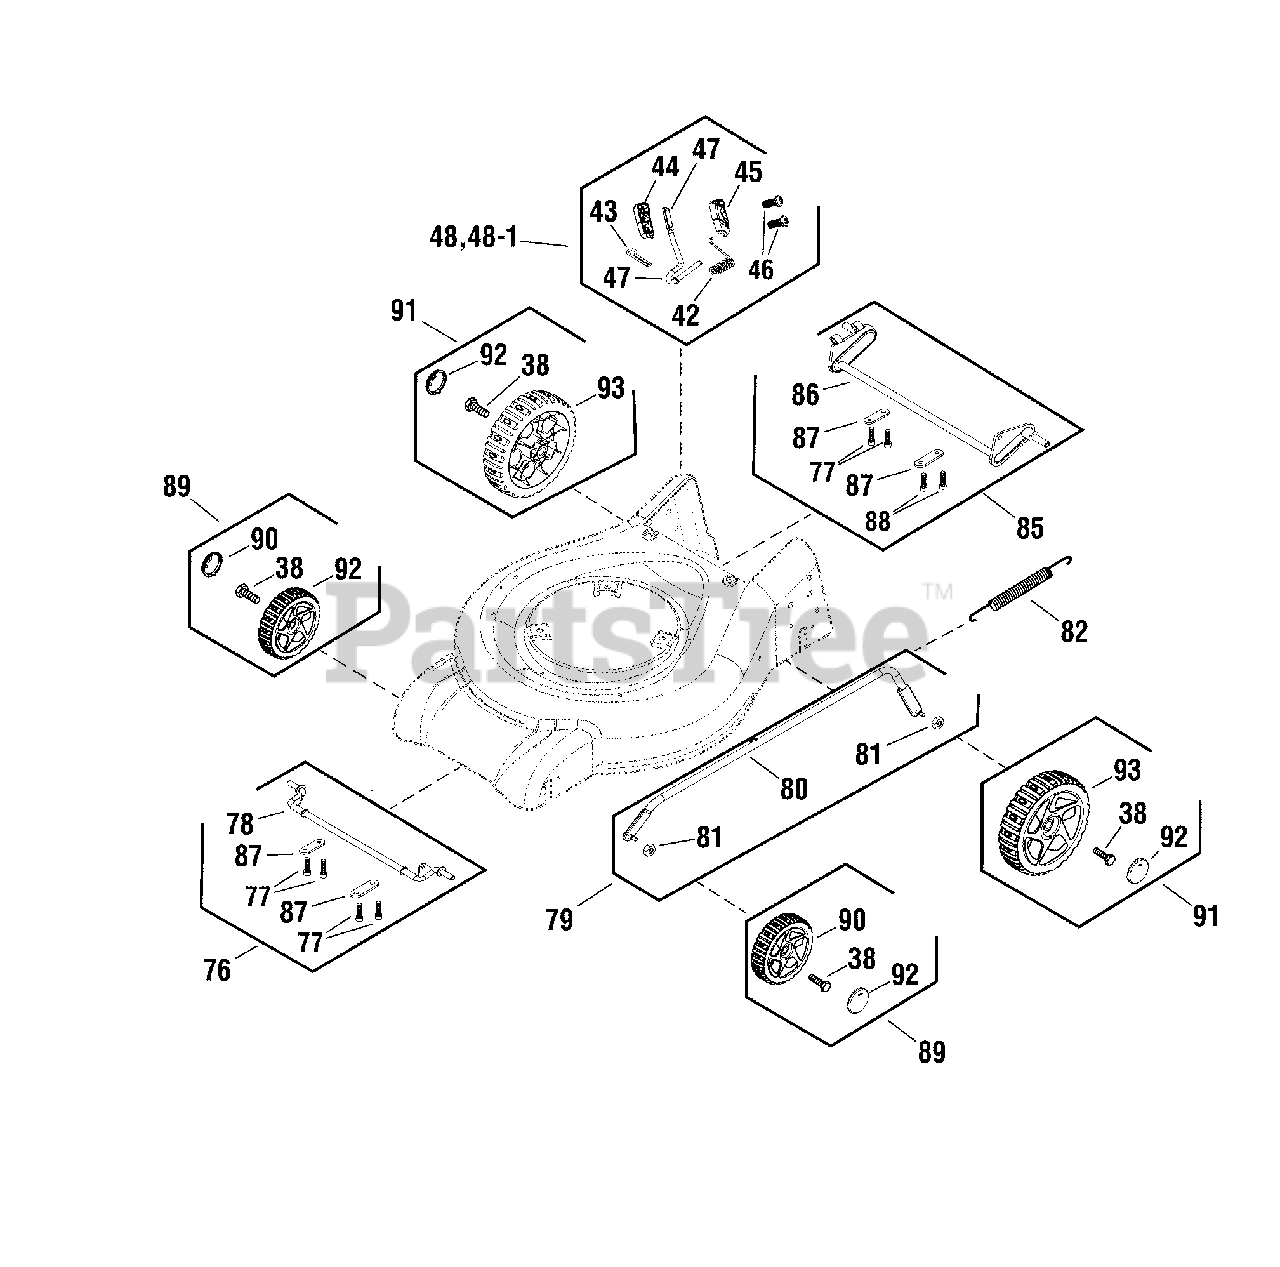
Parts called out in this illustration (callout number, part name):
38	BOLT
40	GASKET
42	SPRING
43	PIN
44	SHELL, LEFT
45	SHELL, RIGHT
46	SCREW
48	ASSEMBLY, HEIGHT ADJUST BAR, NA
48-1	ASSEMBLY, HEIGHT ADJUST BAR, EU
49	ROD, ADJUST
76	KIT, FRONT AXLE
77	SCREW
78	SHAFT, FRONT
79	KIT, HEIGHT ADJUST, NA & EU
80	ROD, CONNNECTING
81	NUT
82	KIT, SPRING
85	KIT, BACK AXLE
86	SHAFT, BACK
87	TABLET
88	SCREW
89	KIT, 8" WHEEL, NA & EU
90	WHEEL, 8"
91	KIT, 10" WHEEL, NA & EU
92	WHEEL COVER
93	WHEEL, 10"
